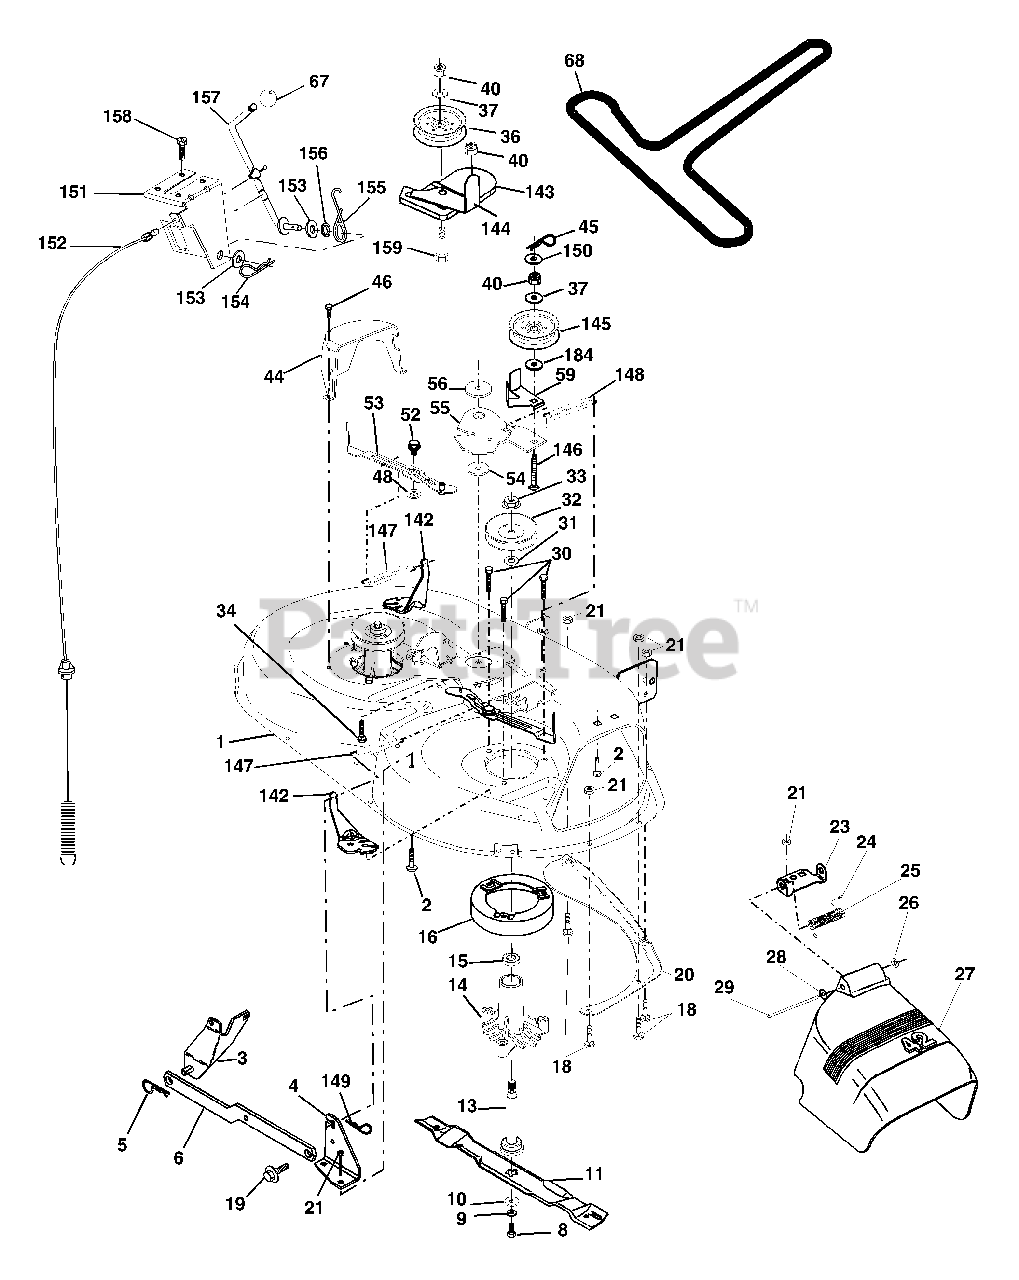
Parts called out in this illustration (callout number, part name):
1	Mower Deck Assembly, 42"
2	Bolt
3	Bracket Asm Fr. Sway Bar 3/42
4	Bracket Asm Deck 42" Sway Bar
5	Retainer Spring
6	Bar Sway Deck
8	Bolt 3/8-24 x 25 Grade 8 patched
9	Washer, Lock
10	Washer, Hardened
11	Blade, 42" Mulching Std
11	Blade, 42" Mulching Premium
11	Blade, 42" Hi-Lift
13	Shaft Assembly, Mandrel, Vented
14	Housing, Mandrel, Vented
15	Bearing, Ball, Mandrel
16	Stripper, Mandrel Deck
18	Bolt, Carriage 5/16-18 x 5/8
19	Bolt, Shoulder
20	Baffle, Vortex
21	Nut
23	Bracket, Deflector Mower 42"
24	Cap, Sleeve 80 x 112 Blk Mower
25	Spring, Torsion, Deflector 2 52
26	Nut, Push Phos & Oil
27	Shield, Deflector 42" Blk
28	Washer 11/32 x 5/8 x 16 Ga.
29	Rod, Hinge 42" 6 75 W/G
30	Screw Thdrol Washer Head
31	Washer, Spacer Mower Vented
32	Pulley, Mandrel
33	Nut, Toplock 9/16 Flange
34	Bolt
36	Pulley, Idler, Flat
37	Washer 13/32 x 13/16 x 16 Ga.
40	Nut
44	Guard, Mandrel, LH
45	Retainer
46	Screw, Thdrol 1/4-20 x 5/8 T
48	Washer, Hardened
52	Bolt, Shoulder 5/16-18 UNC
53	Arm Assembly, Pad, Brake
54	Washer, Hardened
55	Arm, Idler
56	Spacer, Retainer
59	Guard TUV Idler
67	Knob
68	V-Belt, 42" Mower
142	Arm Spring Brake Mower
143	Bracket Arm Idler 42"
144	Keeper Belt 42" Clutch Cable
145	Pulley Idler Flat
146	Bolt Carriage Idler
147	Spring Extension
148	Spring Return Idler
149	Retainer Spring Yellow
150	Washer 9/32 x 3/4 x 16 Ga.
151	Bracket Clutch Cable
152	Clutch Cable 42"
153	Washer Flat 3/8" Type B
154	Spring Retainer
155	Spring Retention LVR CLTCH CAB
156	Spacer Clutch Cable
157	Rod Clutch Cable 3/8"
158	Screw Hex Thd Cut 1/4-20 x 1/2
159	Bolt Rdhd Sqn 3/8-16 UNC x 1-3/4
184	Washer 13/32 x 7/8 x 10 Ga.
